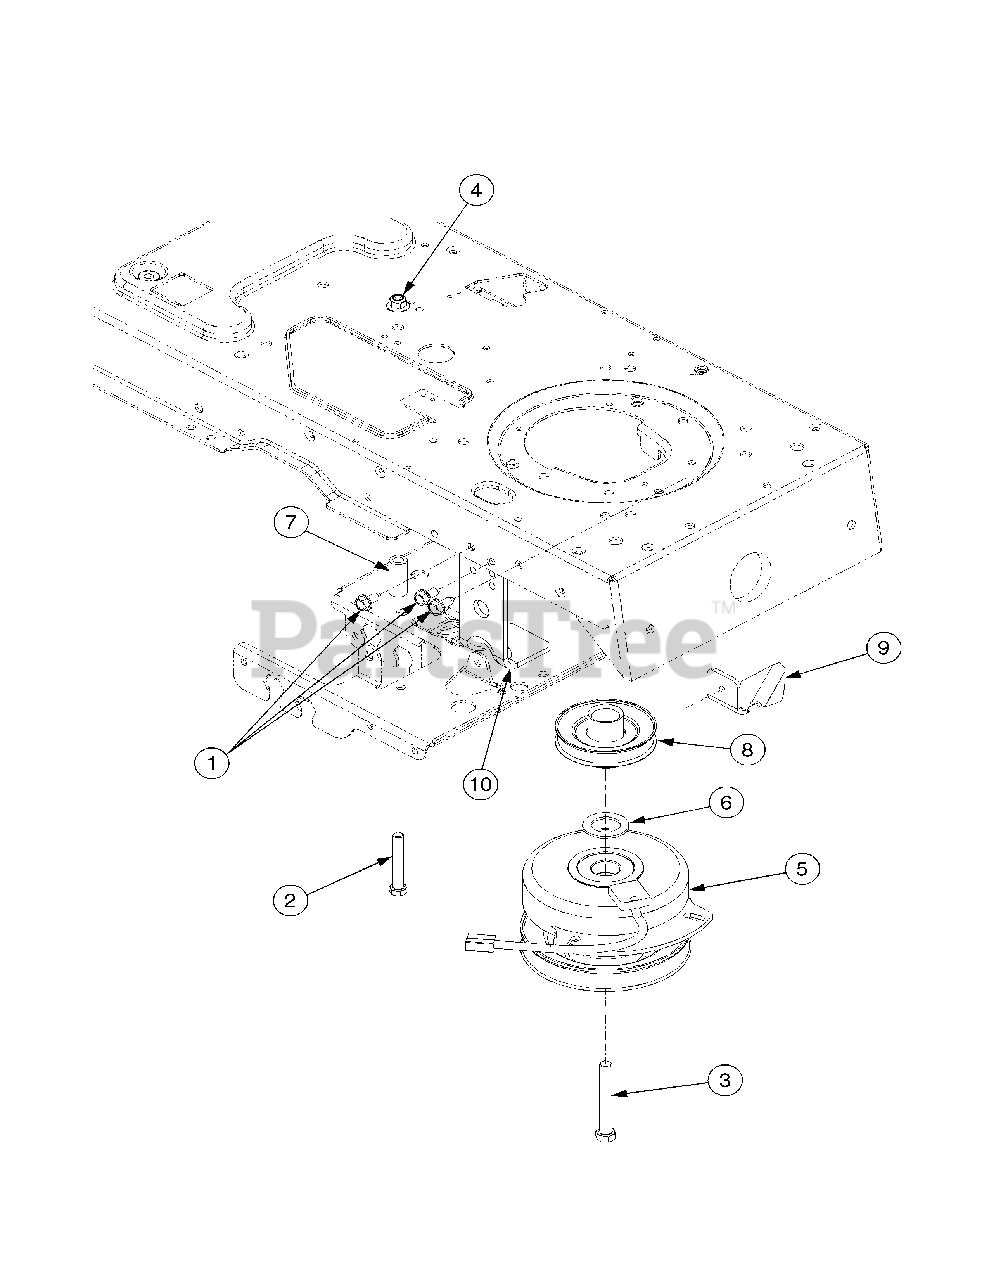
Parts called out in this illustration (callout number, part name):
1	Screw, Hex Wash Hd Tapp, 5/16-12 x .75
2	Screw, Hex Cap, 3/8-16 x 2.5 GR5
3	Screw, Hex Lock, 7/16-20 x 3.25 GR5
4	Nut, Flange Insert Lock, 3/8-16 GrF
5	Clutch, Electric PTO
6	Washer, Flat 1.031 x 1.62 x .095
7	Spacer, 3/8 x .635 x 1.54
8	Pulley,
